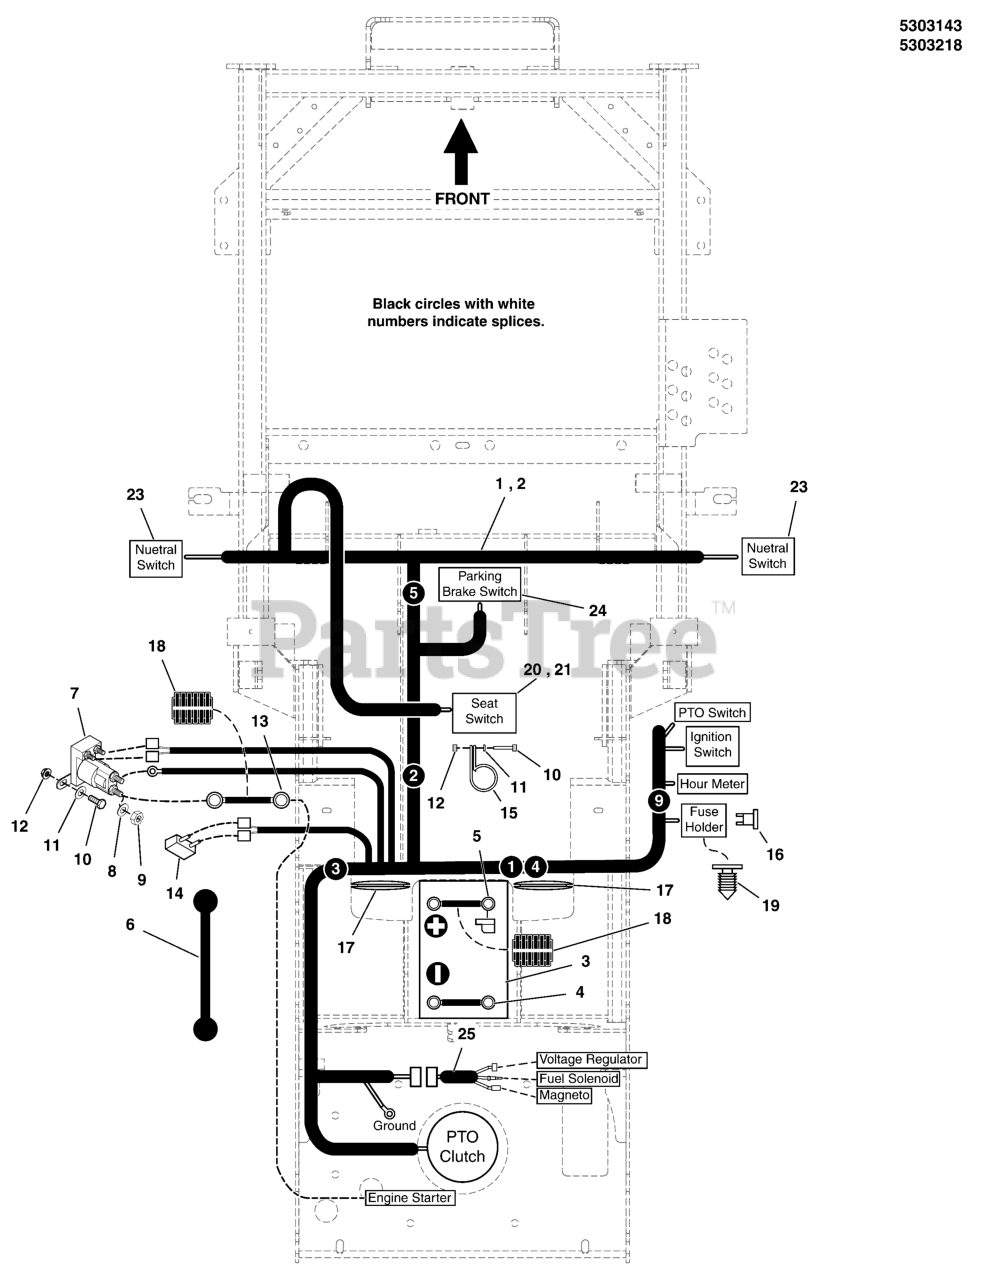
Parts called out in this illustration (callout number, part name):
1	WIRE HARNESS, C TURF,WARNER, IS600/IS700
3	BATTERY, WET (BCIU1, 340 CCA)
4	BATTERY CABLE, NEGATIVE, 14
5	BATTERY CABLE, POSITIVE, 22
6	STRAP-BLACK RUBB
7	SOLENOID-4 POLE 12 VOLT DC (TROMBETTA)
8	WASHER, 5/16 LIGHT LOCK
9	NUT, 5/16-24 JAM
10	BOLT, 1/4-20 X 3/4 GD5 YZ
11	WASHER, 1/4 SAE
12	NUT, 1/4-20 HEX SERR. FLANGE
13	BATTERY CABLE, POSITIVE, 22
14	BREAKER-CIRCUIT 12VOLT 20AMPS W/TAB
15	CLAMP, VINYL INSULATED
16	FUSE, ATO 15 AMP
17	GROMMET, 2" ID
18	WIRE LOOM, 3/8 ID X 18 IN
19	FIR TREE MOUNT, PACKARD
20	SWITCH, NC, W/ BOLT-IN BASE
21	SWITCH, NC, W/ TWIST-IN BASE
22	TIE, SELF-LOCKING, 6"
23	SWITCH, PLUNGER, N.O./N.C.
24	SWITCH, DP NO/NC SNAP-IN
25	WIRE HARNESS, JUMPER, KAWI
